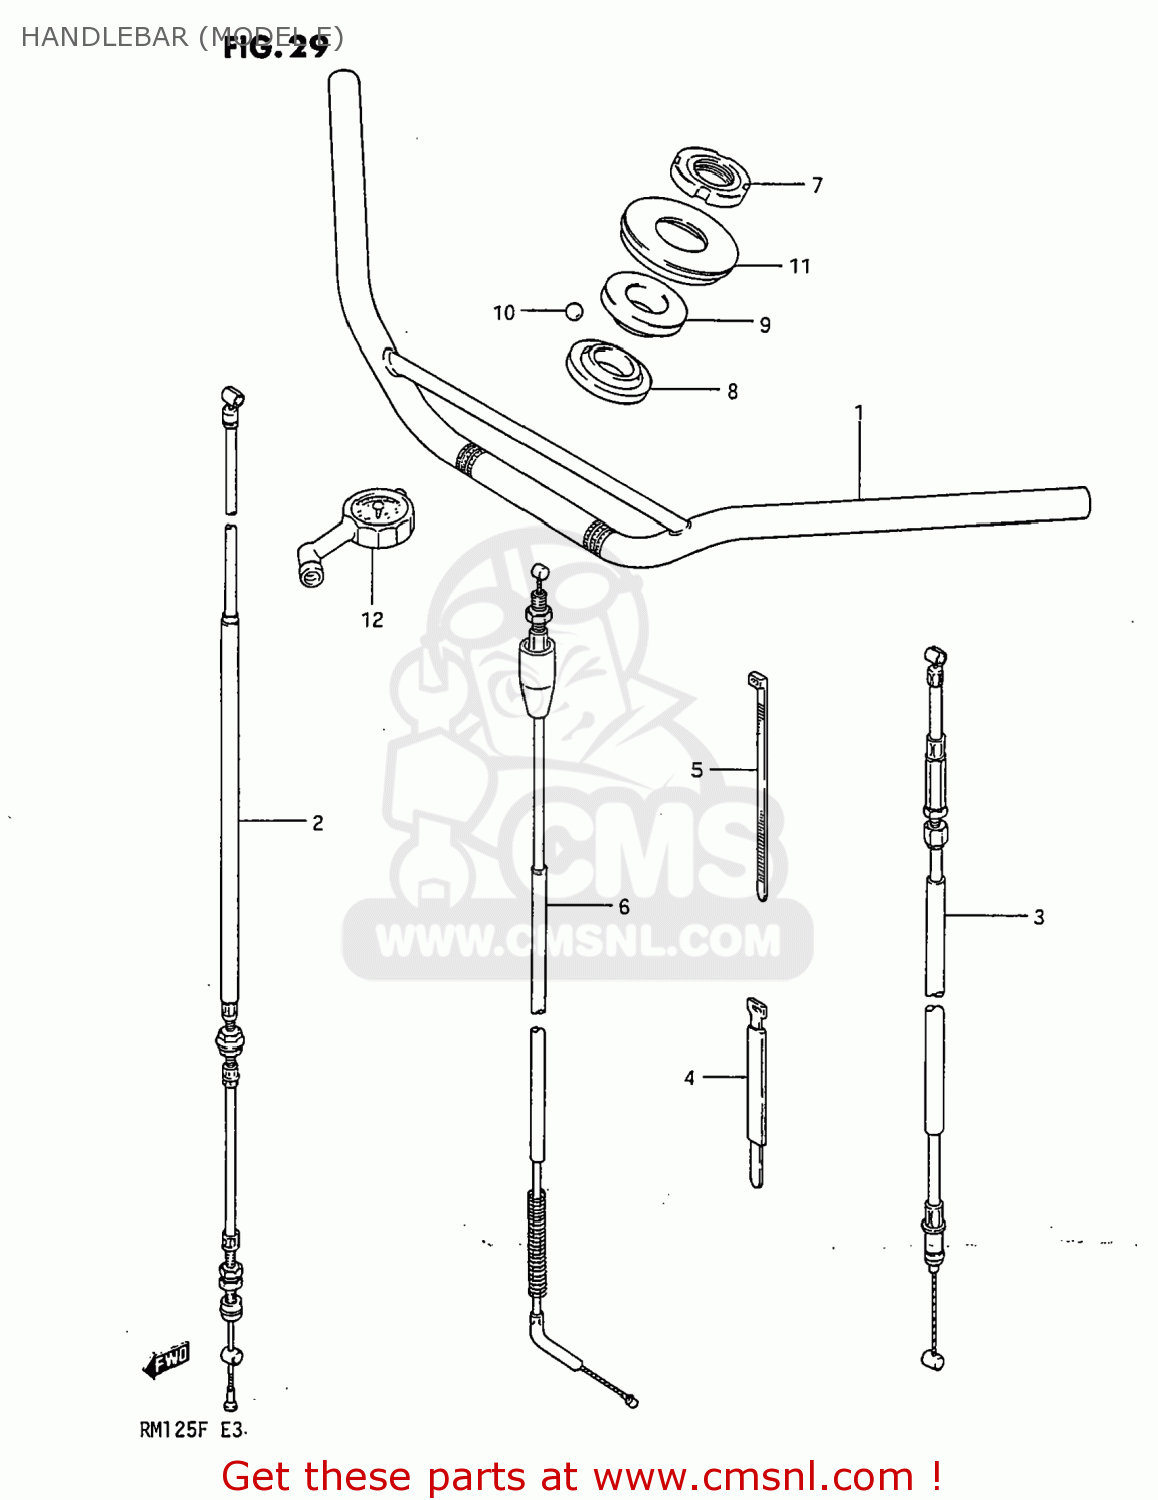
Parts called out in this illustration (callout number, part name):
1	HANDLEBAR
2	CABLE,FRONT BRAKE
3	CABLE ASSY,CLUTCH
4	CLAMP(L:250)
5	CLAMP(L:235)
6	CABLE ASSEMBLY,THROTTLE
7	NUT,STEERING STEM
8	RACE,STEERING,INNER,UPPER
9	RACE,STEERING,OUTER,UPPER
10	BALL
11	SEAL,STEERING UPR DUST
12	GAUGE ASSY,AIR PRESSURE
